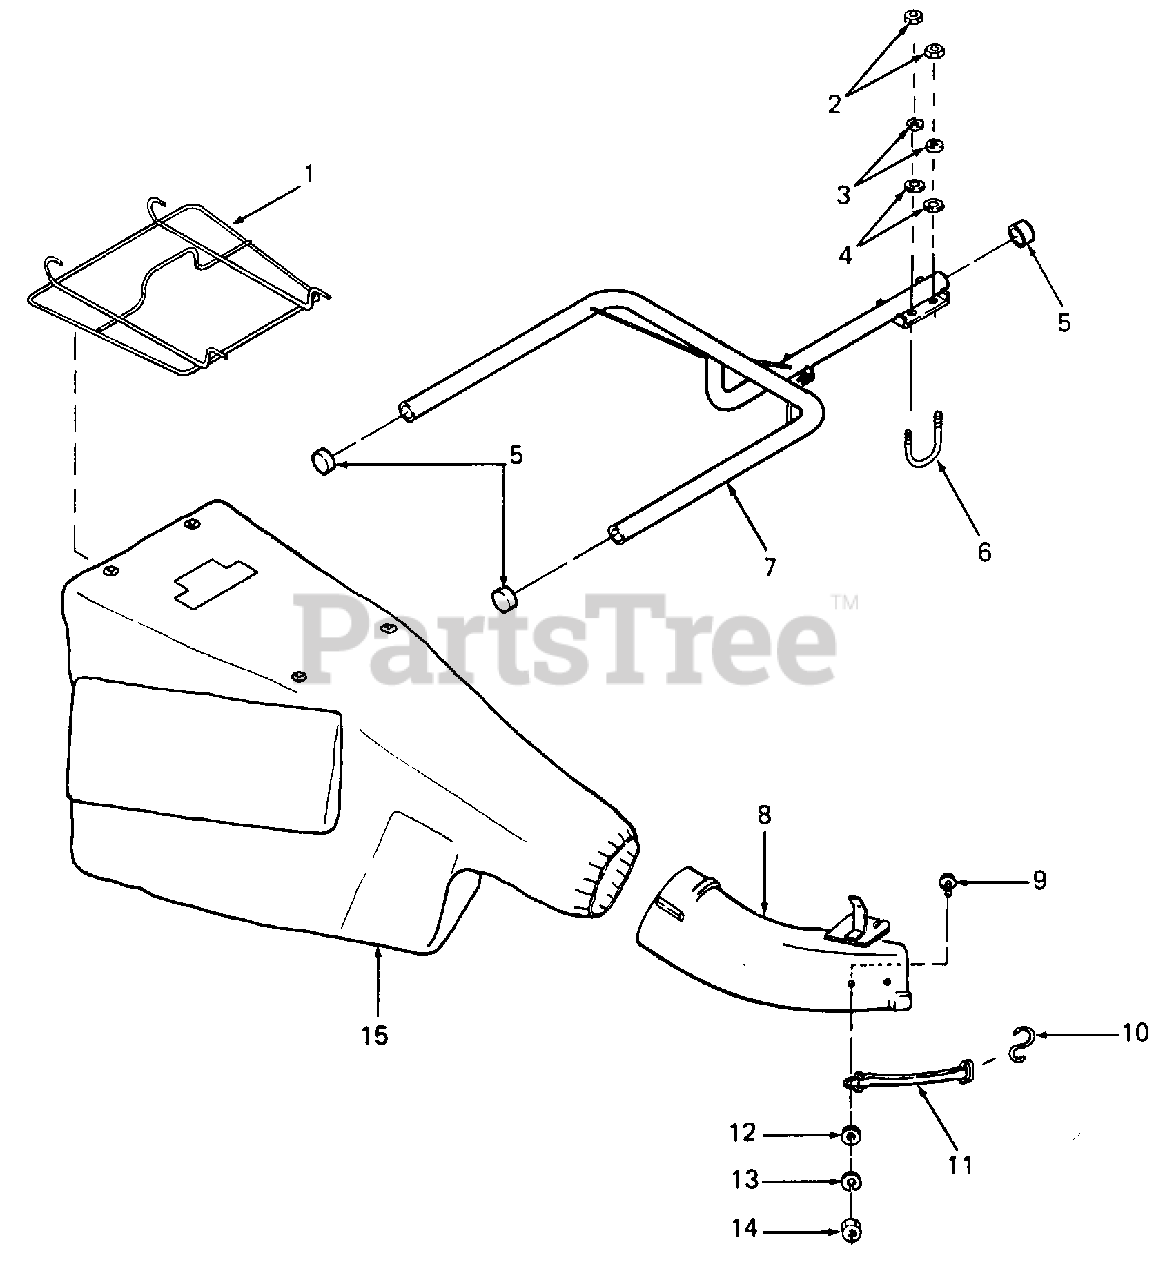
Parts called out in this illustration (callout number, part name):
2	Nut, Hex Plain, 5/16-18
3	Washer, Lock, 5/16 Dia
4	Washer, Flat, 5/16 Dia
7	Catcher Hanger
8	Chute, 38 & 32 Inch
9	Screw, Mach, 1/4-20 X 3/4
11	Retainer Strap Assembly
12	Washer, Flat, 1/4 Dia
13	Washer, Lock, 1/4 Dia
14	Nut, Hex Plain, 1/4-20
